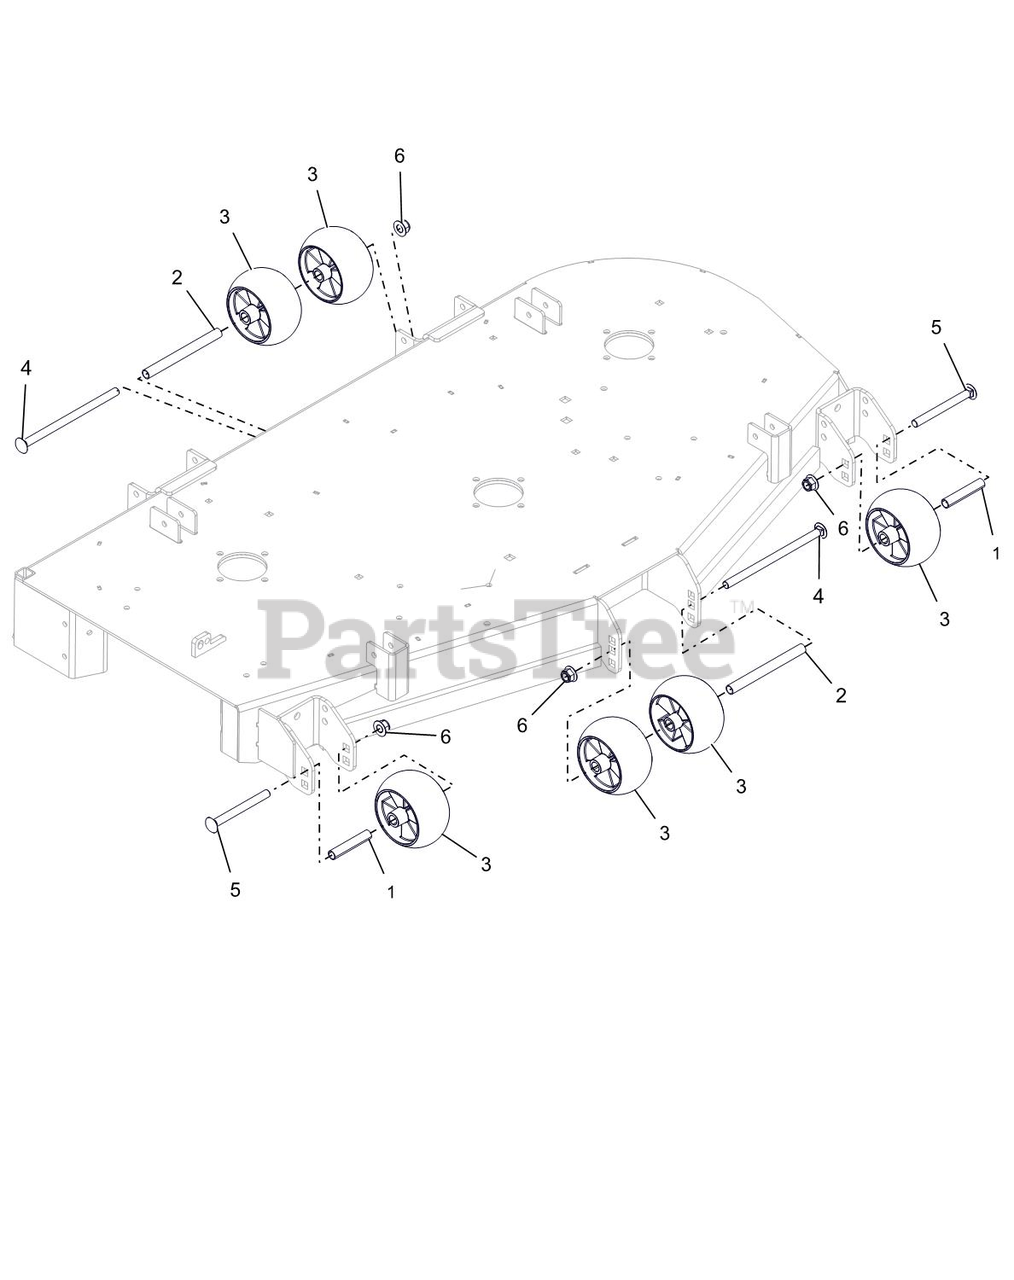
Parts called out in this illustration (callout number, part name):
1	SPACER, .510X.625X3.35
2	SPACER, .510X.625X6.50
3	ANTI-SCALP WHEEL - 5X3 CTR
4	@BLT-RDHDSQNK .50-13X8.50 G5YZ
5	BLT-RDHDSQNK .50-13X5.00 GR5YZ
6	@NUT-LK-NYL-FLG .50-13 YWZC
